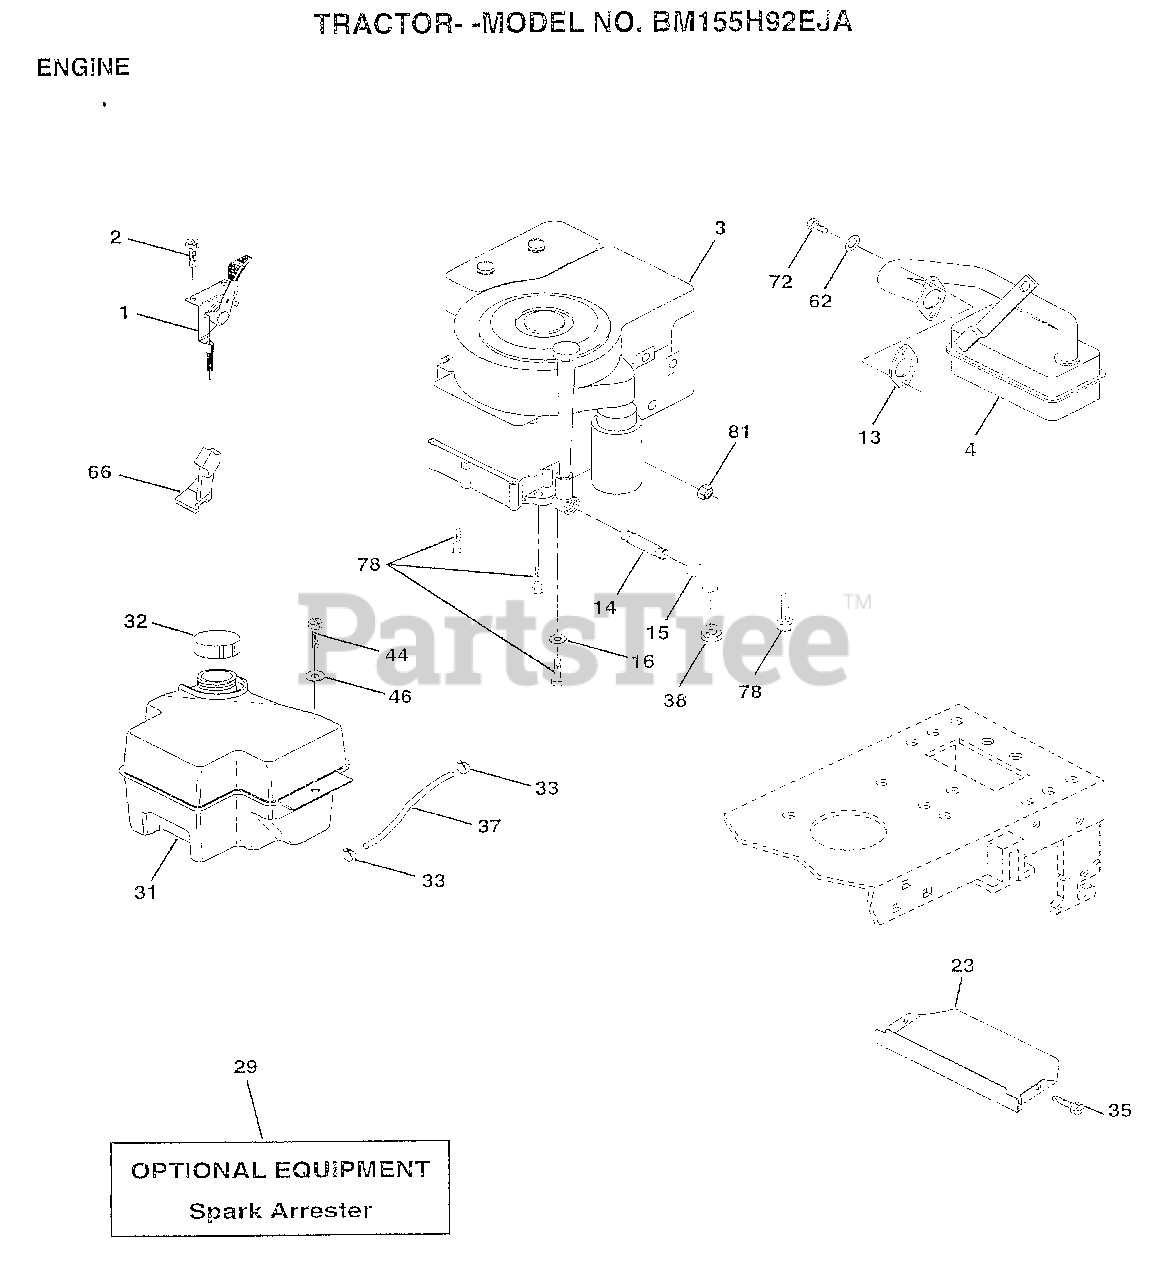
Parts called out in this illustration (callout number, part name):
1	CONTROL.THTL.23.5
2	SCREW LT
4	MUFFLER
14	PIPE NIPPLE
15	ELBOW
16	LOCKWASHER
23	SHIELD.BRN/DBR.GD
31	TANK.FUEL.FRONT.
32	CAP ASM FUEL
33	HOSE CLAMP
35	SCREW
37	LINE FUEL
44	SCREW HEX CRT
46	WASHER
62	LOCKWASHER
66	"STOP,DASH THROTT"
72	SCREW
78	SCREW
81	NUT
